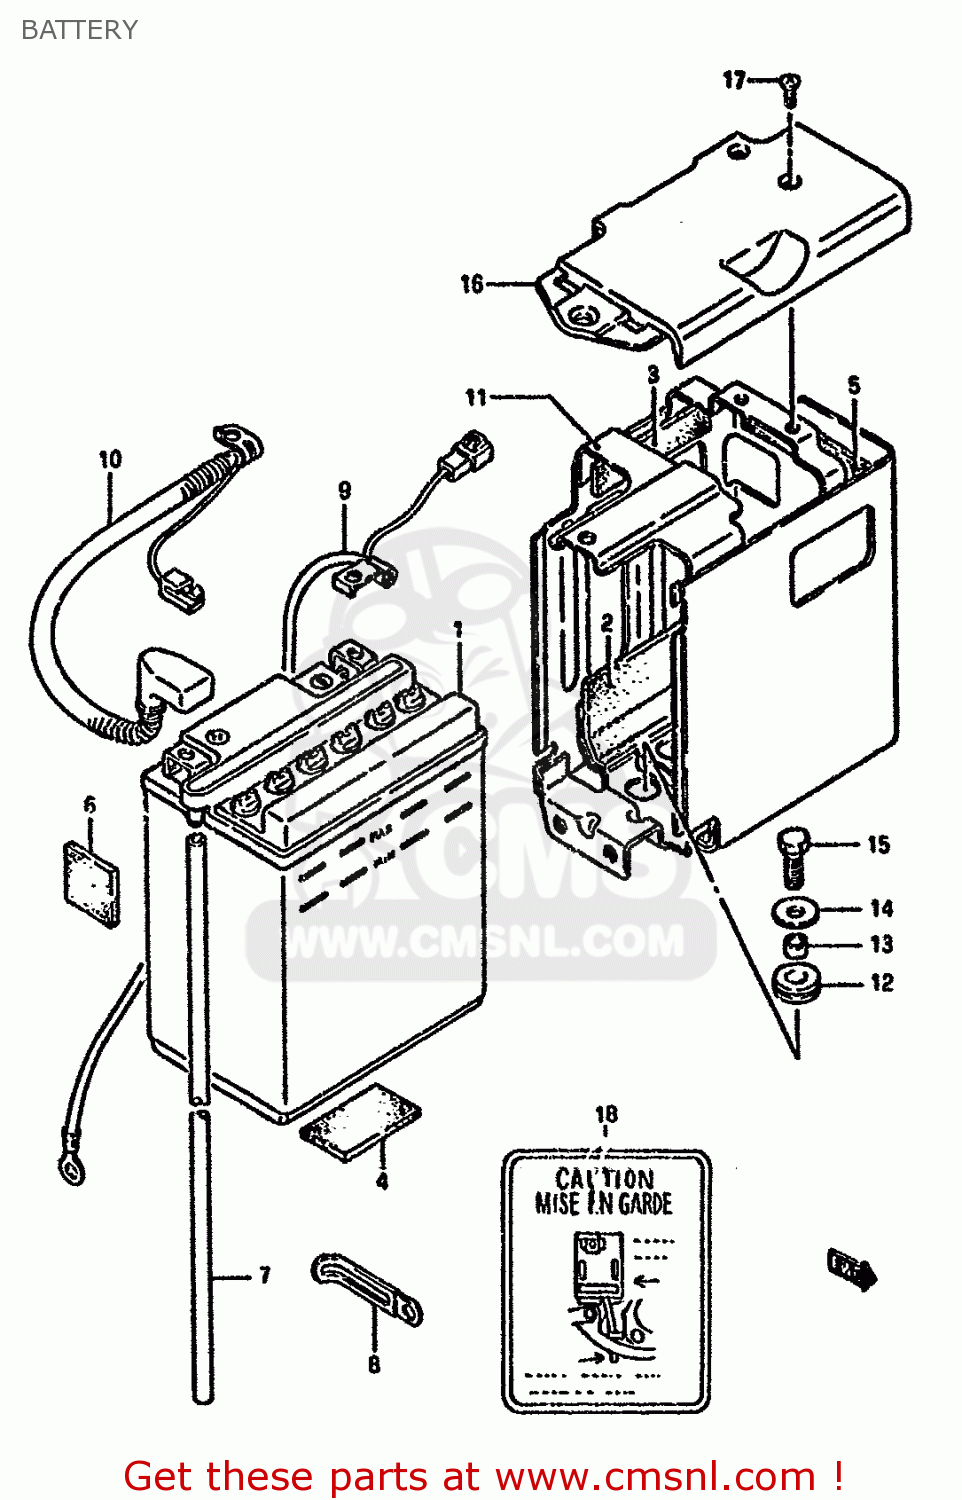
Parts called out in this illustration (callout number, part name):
1	BATTERY(YB14L-B2,12V14.7AH)
2	PROTECTOR(170X95X3.0)
3	PROTECTOR,20X9
4	CUSHION(30X50X3)
5	PROTECTOR(20X90)X2
6	PROTECTOR,BATTERY
7	HOSE,BATTERY EXHAUST(L:780)
8	CLAMP
9	WIRE,BATTERY MINUS
10	WIRE,BATTERY PLUS LEAD
11	HOLDER COMP,BATTERY
12	CUSHION
13	SPACER
14	WASHER
15	SCREW
16	COVER,BATTERY
17	SCREW
18	PLATE,BATTERY CAUTION
